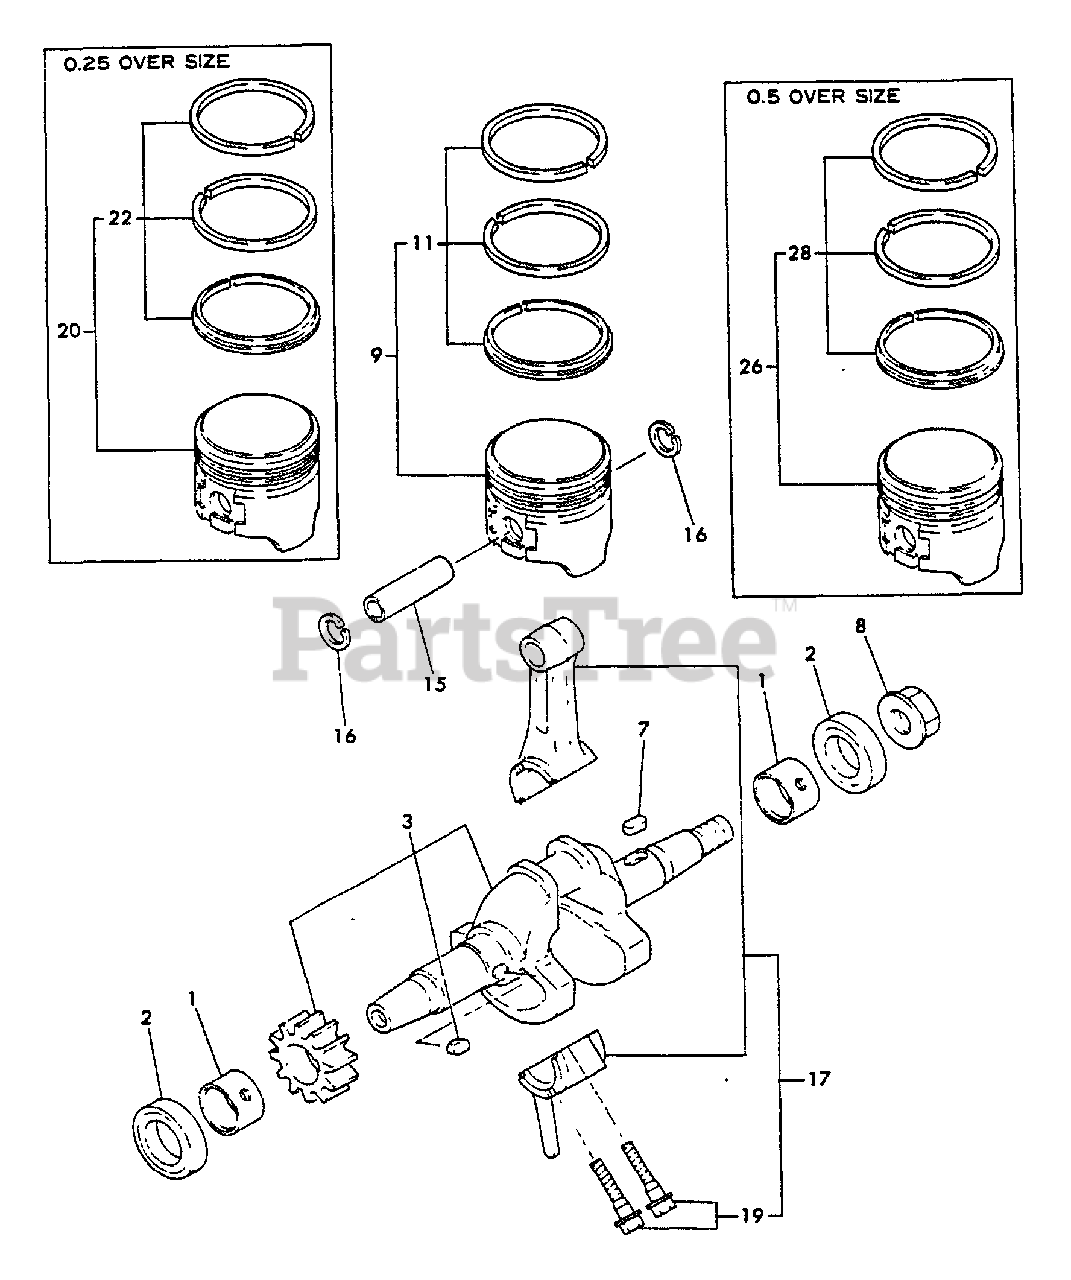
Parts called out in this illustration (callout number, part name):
1	MAIN BEARING
2	SEAL, OIL
3	CRANKSHAFT ASSY
7	KEY - 4X10
8	NUT - 10 -- FLANGE
9	PISTON ASSY
11	PISTON RING SET
15	PIN, PISTON
16	RING, RETAINING - 10
17	CONNECTING ROD ASSY
19	BOLT, ROD
20	PISTON ASSY O.S. = 0.2
22	RING SET O.S. = 0.25
26	PISTON ASSY
28	RING SET O.S. = O.5
